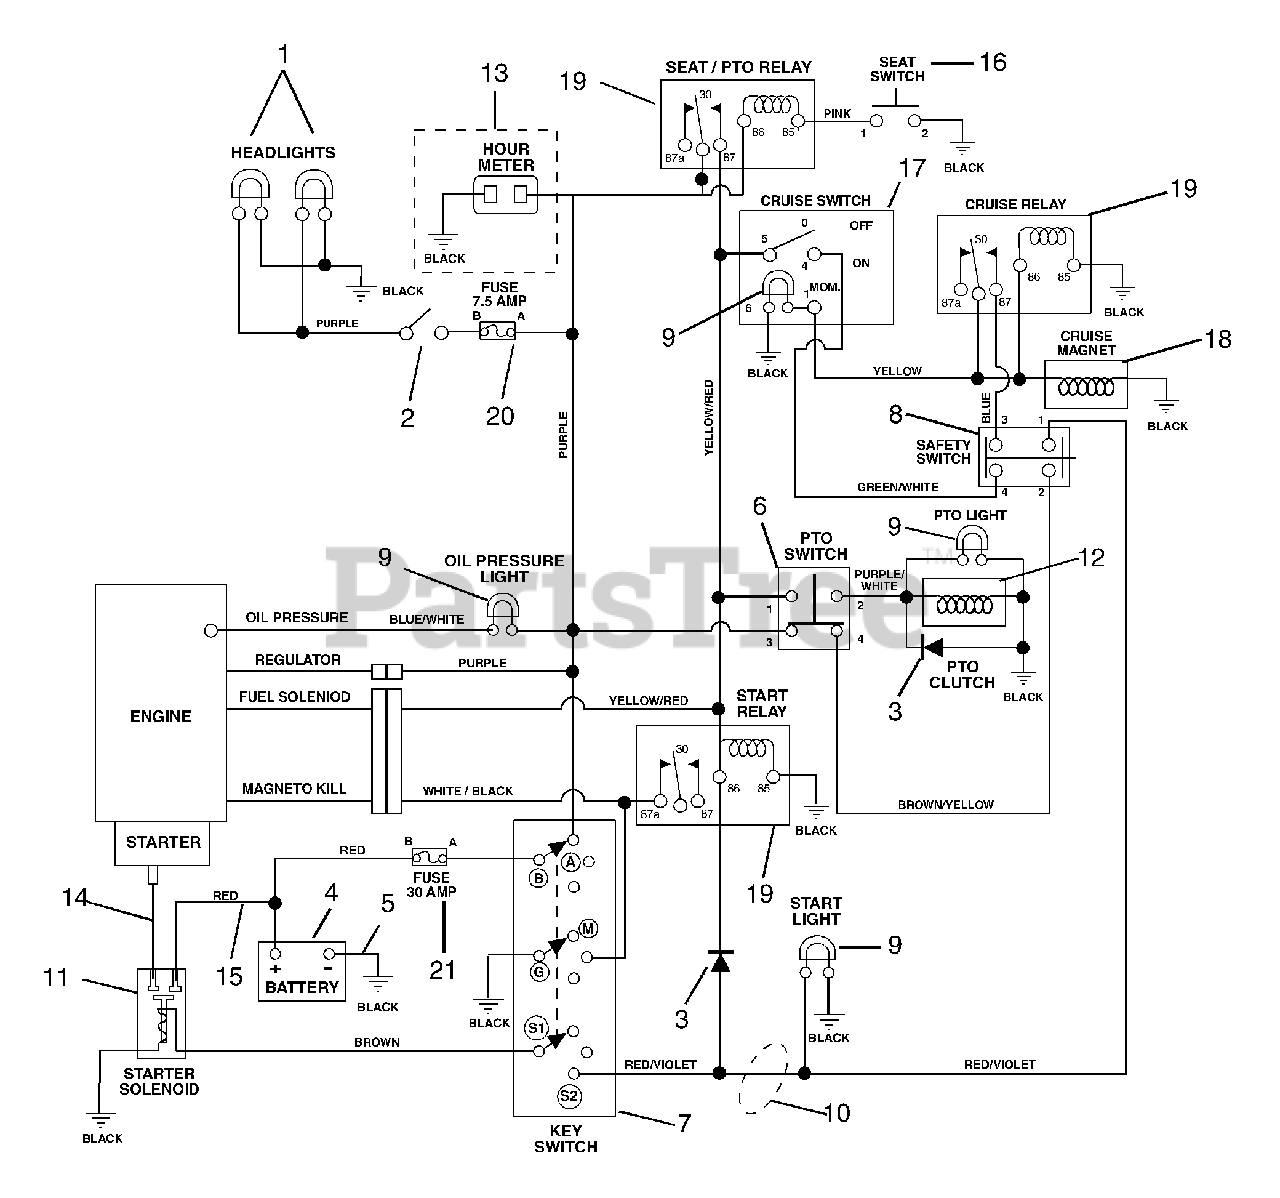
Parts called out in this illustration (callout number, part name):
1	HEADLIGHT- RH
2	SWITCH - LIGHT
3	MOLDED DIODE PLUG 1 AMP
4	BATTERY W/TUBE
5	GROUND CABLE .31X22.00X.31
6	PTO SWITCH ASSEMBLY
7	KEY SWITCH
8	SWITCH,INTERLOCK
9	#194 Bulb
10	HARNESS, WIRING 1440 B&S
11	SOLENOID
12	ELECTRIC CLUTCH/BRAKE (3.4AMP)
13	HOURMETER KIT- SIERRA
14	START CABLE 22"
15	STARTER CABLE 6.75"
16	SWITCH- SEAT
17	SWITCH - CRUISE
19	RELAY
20	FUSE, 7.5 AMP
21	FUSE, 30 AMP.
